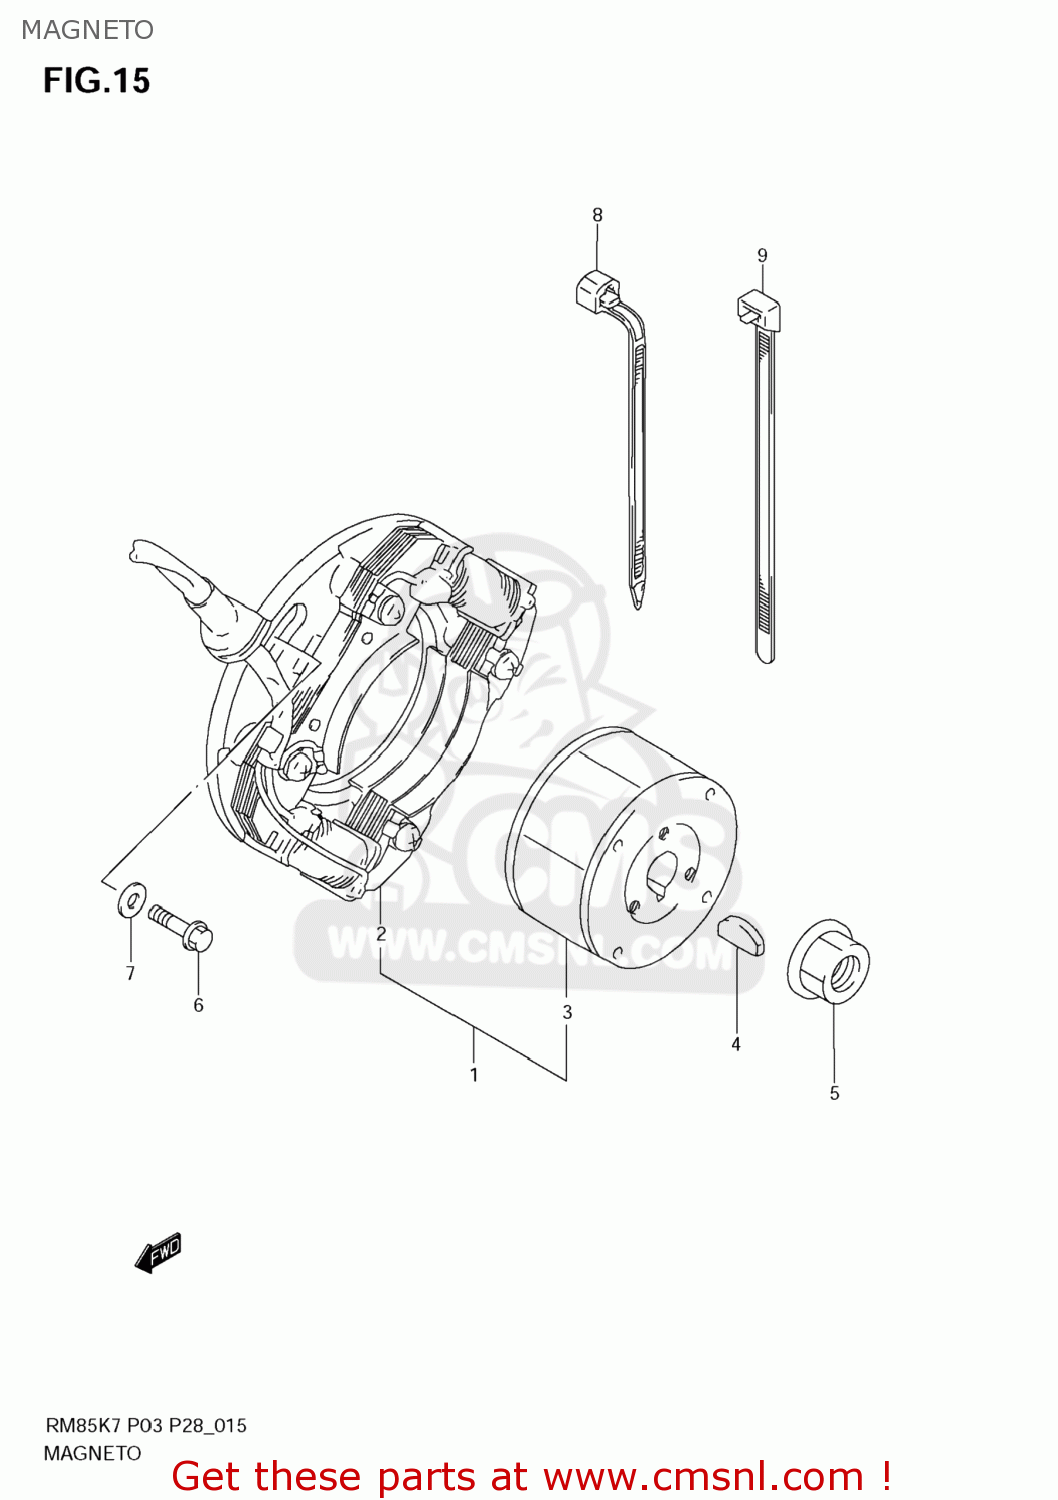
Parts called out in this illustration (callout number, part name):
1	MAGNETO ASSY
2	STARTER ASSY
3	ROTOR ASSY
4	KEY
5	NUT
6	BOLT
7	WASHER
8	CLAMP(L:165)
9	CLAMP(L:150)
